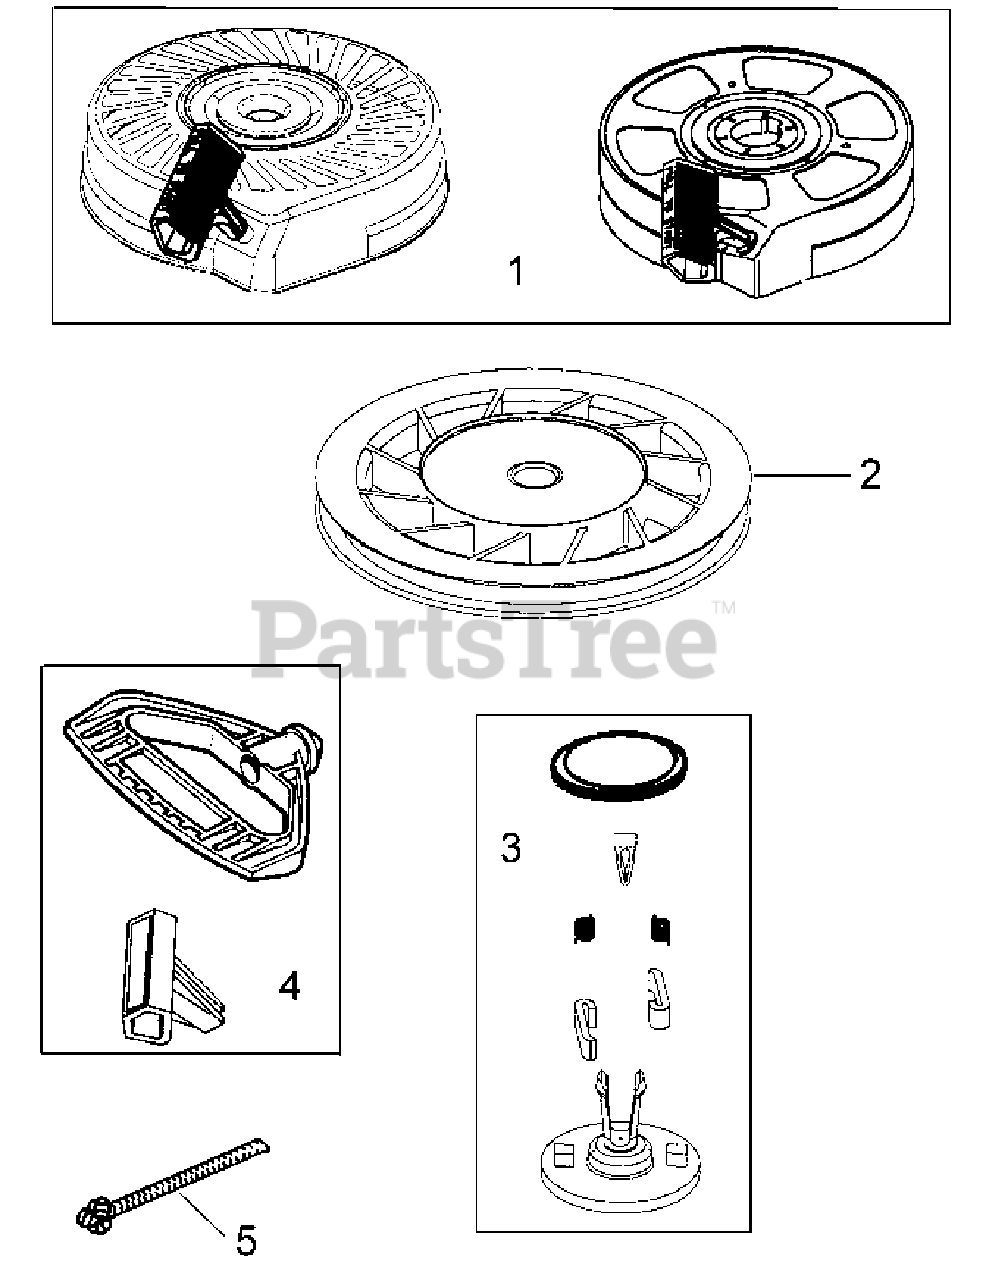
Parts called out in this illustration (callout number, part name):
1	Rewind Starter
2	Pulley & Rewind Spring Ass'y
3	Repair Kit
4	Starter Handle (standard)
5	98" Starter Rope (cut to length)
